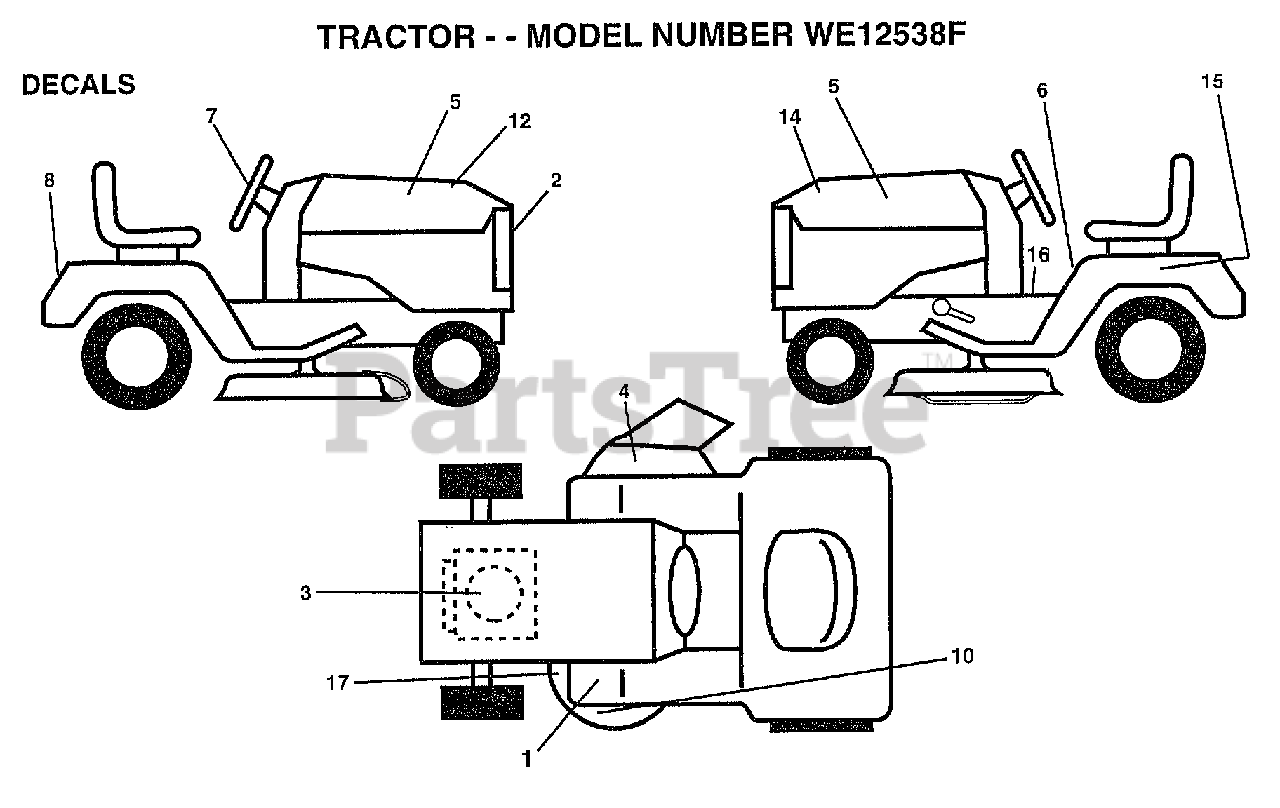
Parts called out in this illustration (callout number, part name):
1	DECAL T
2	DECAL, GRILLE LENS
4	"DECAL, WARNING"
5	DECAL
6	DECAL.CAUT.ENG/FR
7	DECAL, INS STRG WH
8	DECAL.FENDER.LOGO
10	DECAL, DECK GRASSEATER
12	DECAL.HOOD.RH.
14	DECAL.HOOD.LH
15	DECAL.BATRY.3-3908
16	"DECAL.OPER,SDL"
17	DECAL
